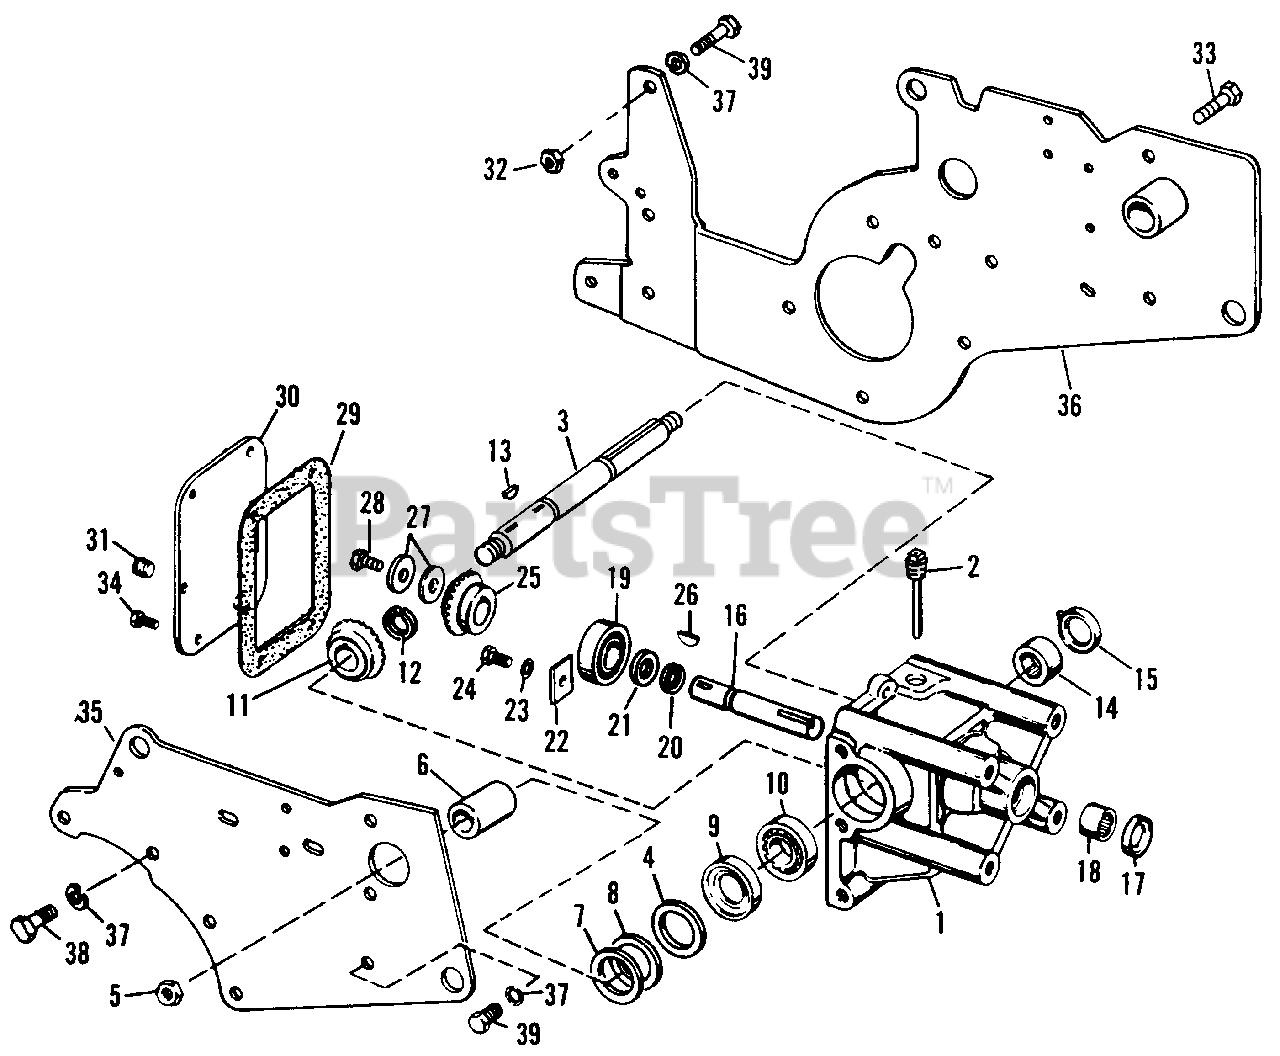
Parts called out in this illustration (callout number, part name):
1	Bevel Gear Housing, w/Bearings
2	Filler Plug Assy.
3	Driven Shaft
5	Hex Jam Nut, 3/4"-16
7	Shim (As Required)
10	Ball Bearing
11	Bevel Driven Gear
12	Retaining Ring
14	Needle Bearing
16	Drive Shaft
18	Needle Bearing
19	Ball Bearing
20	Retaining Ring
22	Bearing Clamp Plate
23	Lockwasher, 5/16"
24	Hex Capscrew, 5/16"-18 x 5/8"
25	Bevel Driven Gear
27	Washer, Compression
28	Hex Capscrew, 5/16"-18 x 3/4"
31	Pipe Plug, 1/4"
32	Full Hex Nut, 7/16"-14
33	Hex Capscrew, 7/16"-x 14-1/4"
34	Hex Capscrew, 1/4"-20 x 5/8"
35	Right Hand Side Plate
36	Left Hand Side Plate
37	Lockwasher, 7/16"
38	Hex Capscrew,7/16"-14 x 1"
39	Hex Capscrew, 7/16"-14 x 1-1/4"
